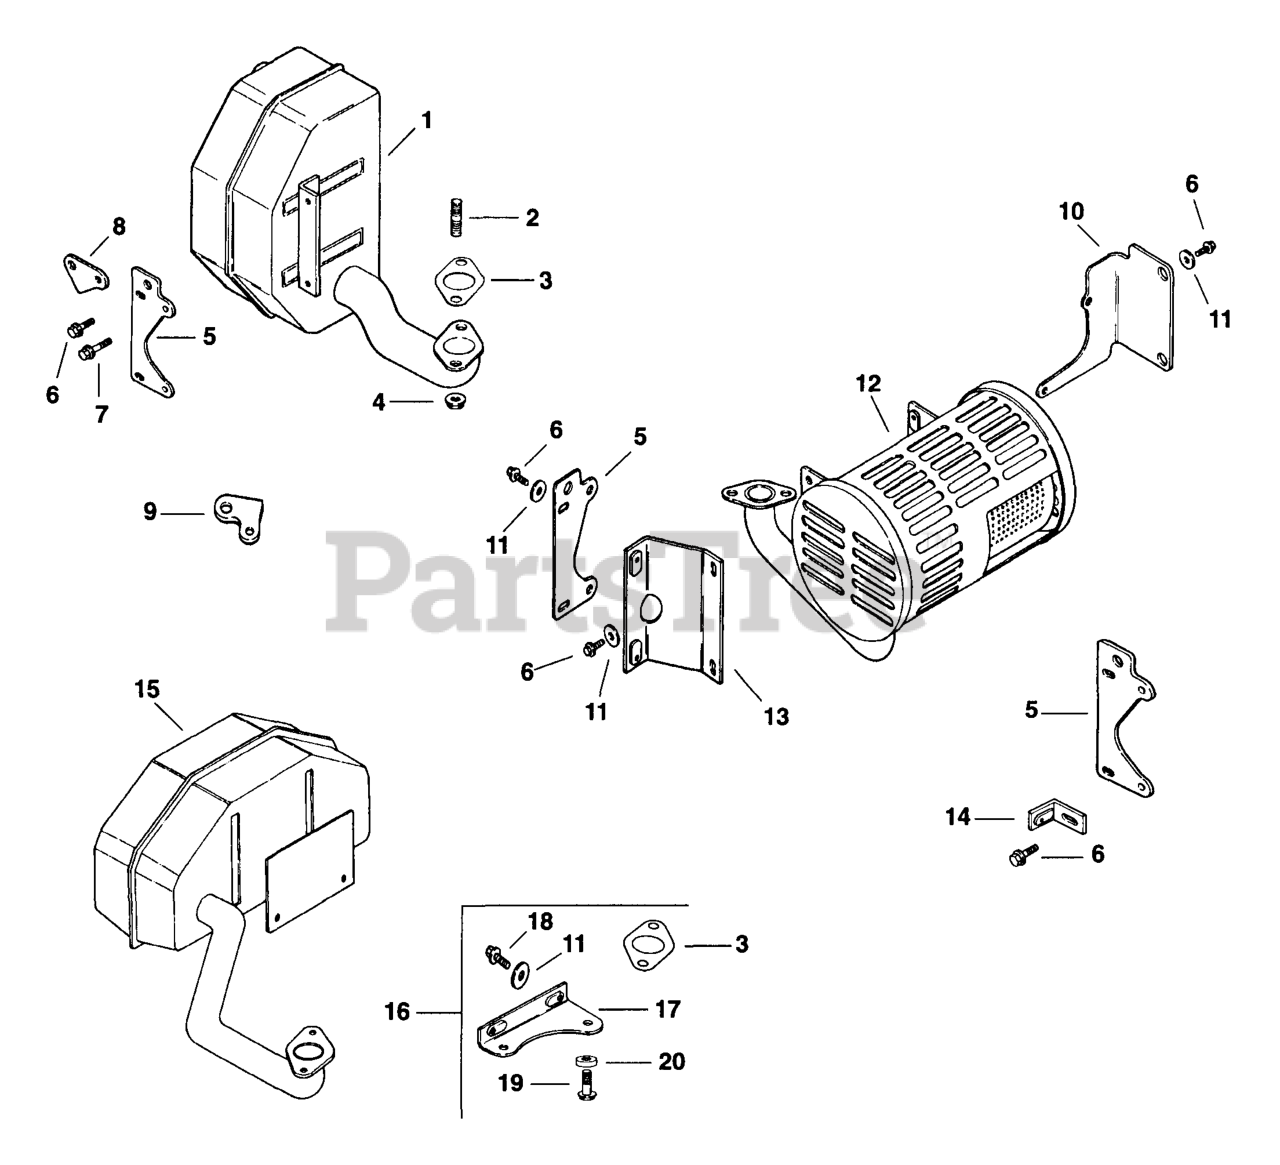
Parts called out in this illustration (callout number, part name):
2	STUD - USE M-829033
3	GASKET, EXHAUST MANIFOLD
4	NUT - USE M-841080
5	BRACKET - USE 12 126 71-S
7	SCREW - USE M-645025
11	WASHER, PLAIN 1/4"
11	WASHER, FLAT 1/4"
